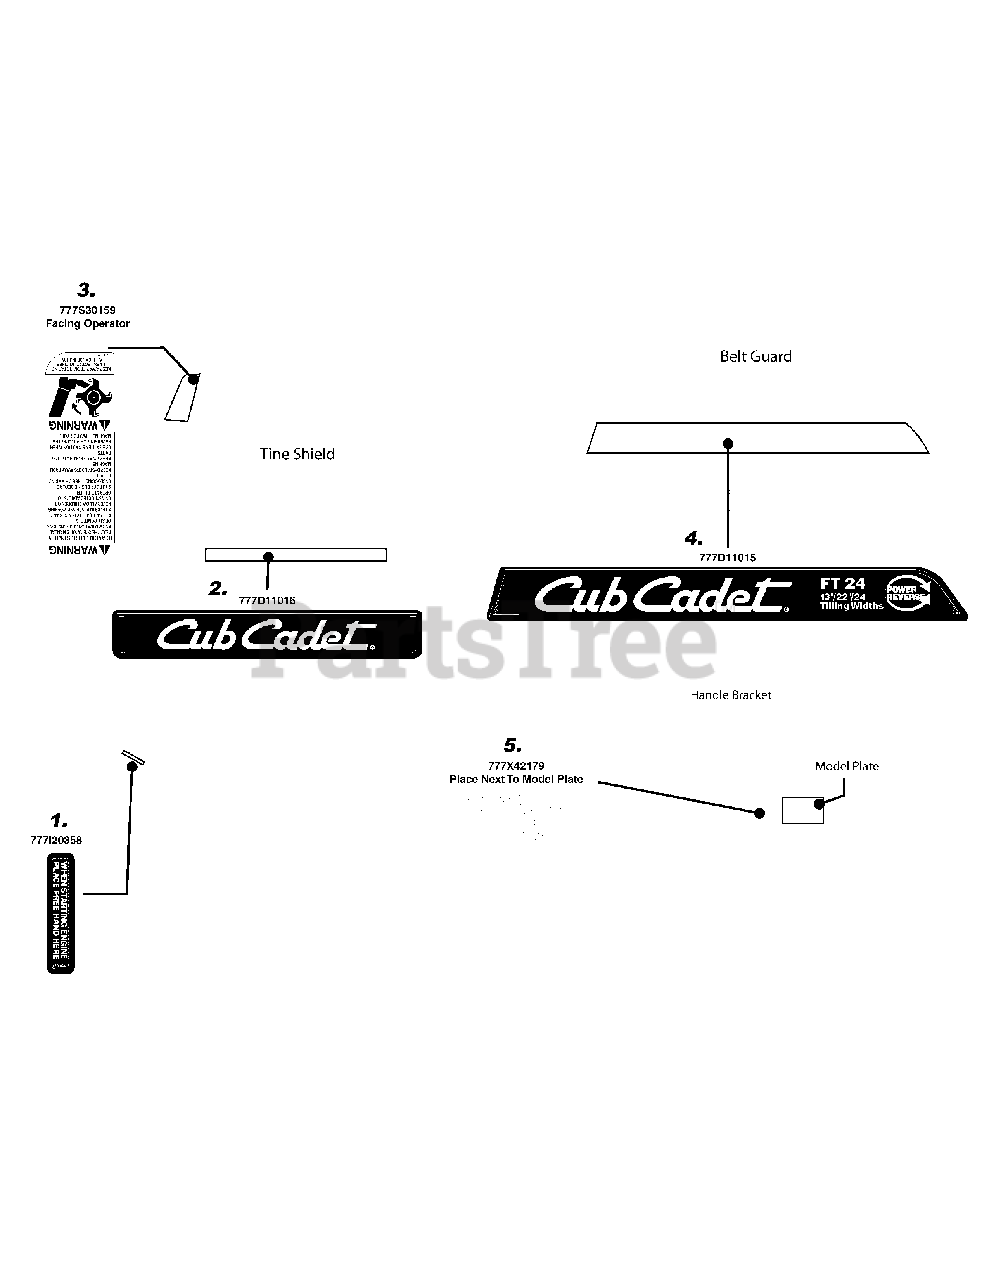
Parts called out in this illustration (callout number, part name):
1	LABEL-PLACE HAND HERE
2	LABEL-TINE SHIELD
3	LABEL-SAFETY/WARNING
4	LABEL-BELT GUARD
5	LABEL-CUB HOTLINE
